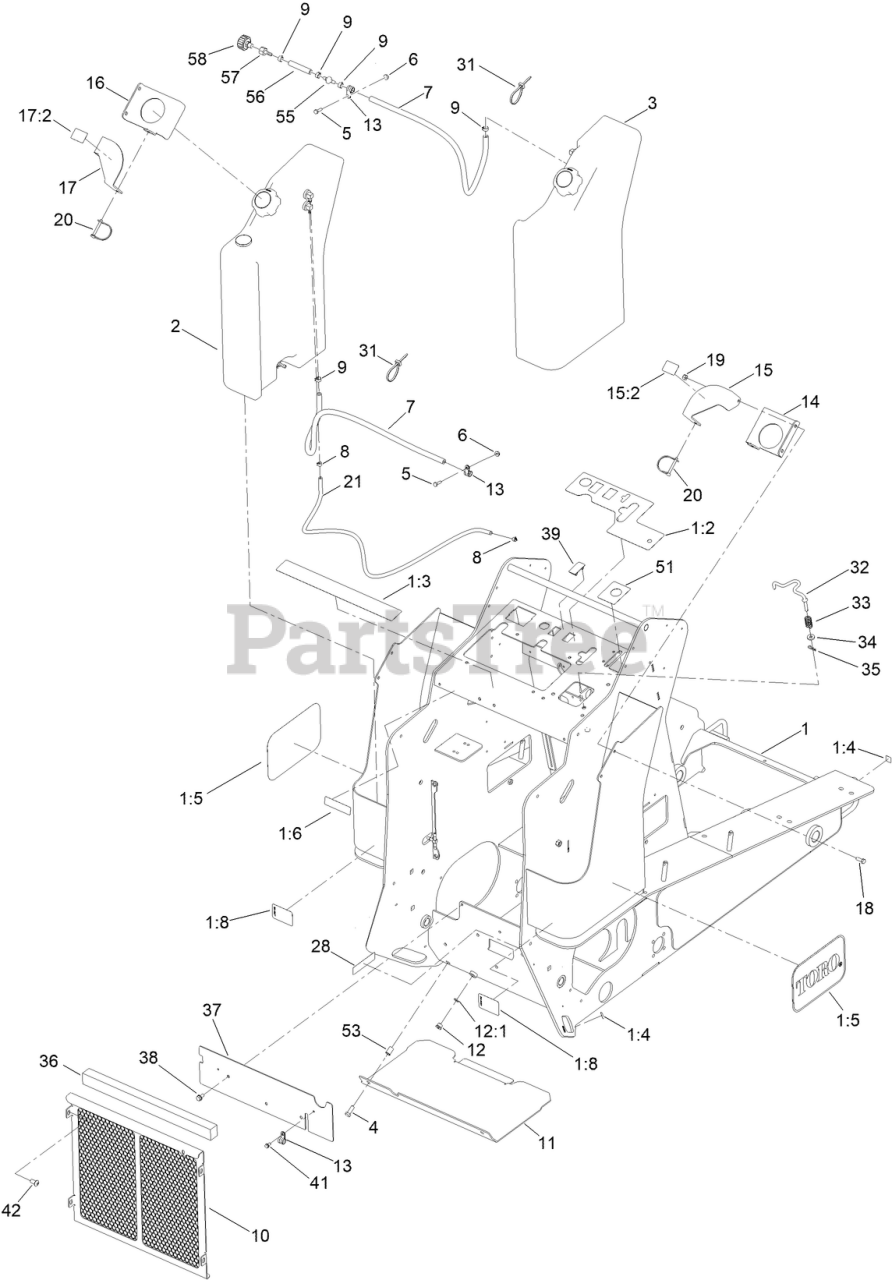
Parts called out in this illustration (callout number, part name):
1	TX1000 FRAME ASM (SERVICE)
1:2	DECAL-CONTROL PANEL
1:3	DECAL-SAFETY
1:4	DECAL-POINT, LIFT
1:5	DECAL
1:6	DECAL-RADIATOR FILL
1:8	REFLECTOR
2	LH FUEL TANK ASM
3	RH FUEL TANK ASM
4	SCREW-HH
5	SCREW-HH
6	NUT-HF
7	HOSE-FUEL
8	CLAMP-HOSE
9	CLAMP-HOSE
10	SCREEN ASM
11	COVER-BOTTOM
12	PLUG-HEX, HOLLOW
12:1	O-RING
13	CLAMP-R
14	PLATE-HOLD DOWN, RH
15	PLATE-LOCK, FUEL CAP, RH
15:2	DECAL-ULTRA LOW SULFUR DIESEL
16	PLATE-HOLD DOWN, LH
17	PLATE-LOCK, FUEL CAP, LH
17:2	DECAL-DIESEL
18	SCREW-HH
19	NUT-LOCK, NI
20	PIN-HITCH
21	HOSE-FUEL
28	DECAL-ARRESTOR, SPARK
31	TIE-CABLE
32	ROD-INTERLOCK
33	SPRING-CONTROL
34	WASHER-FLAT
36	SEAL-FOAM
37	PANEL, FRAME
38	SCREW-HWHTF
39	PLUG-HOLE
41	SCREW-HWH
42	SCREW-HH
51	DECAL-IGNITION SWITCH
53	NUT-CLINCH
55	VALVE-CHECK, FUEL
56	HOSE-FUEL
57	FITTING-STRAIGHT
58	BREATHER
